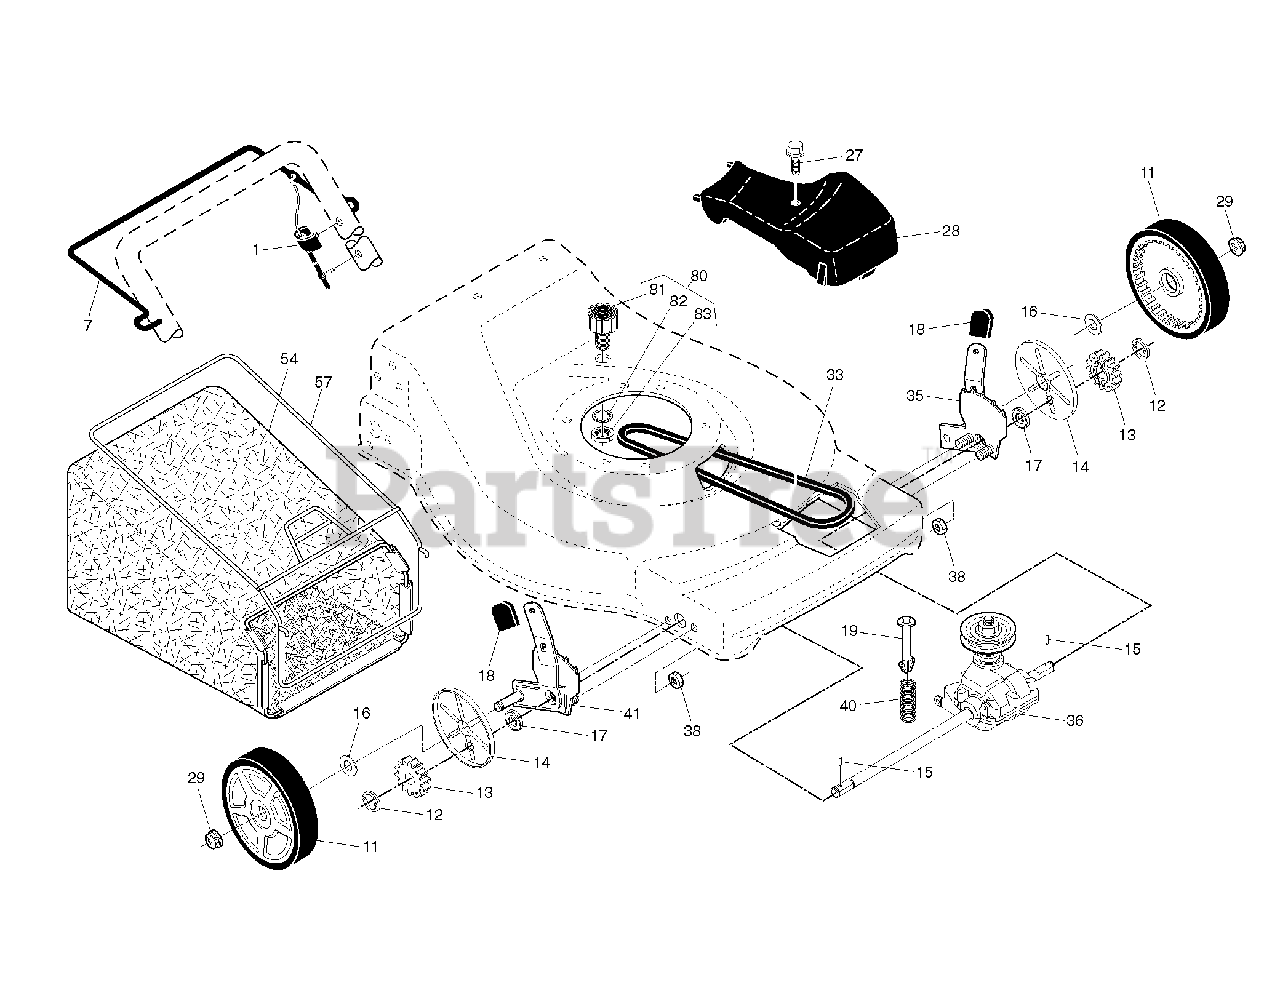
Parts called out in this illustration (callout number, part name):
1	CONTROL.DRIVE.S/SPEED.FWGD
7	BAIL.DRIVE.S/S.ROUND.MARI.21
11	RP.WHEEL.8X1.75.5SPK.RAD3.BLCK
12	E-RING 7/16 RE
13	PINION.14.TEETH.FGD
14	COVER.DUST.WHEEL
15	PAWL, DRIVE
16	WASHER FLUT
17	BEARING.ASM.
18	KNOB.ERGO.DLX.PLAS.MARI.MULTI
19	SPRING RETAINER
27	SCREW, HEX HD TAPPING #10-24 1
28	Drive Cover, Torus B&S Black
29	NUT.HEX.FLANGE.3/8-16.LOCKNUT
33	BELT THERM .32
35	KIT ADJUSTER ASM.438151.
36	TRANSMISSION.22.FGD/W/PULLEY
38	LOCKNUT.NYLOC.1/4-20
40	SPRING.EXTENSION
41	KIT ADJUSTER ASM.438148
54	GBAG.87510416S.BLK.PPR*SUBS/
57	Grass Bag Frame, 22" EZ Empty SC
80	KIT.WASH-OUT.PORT
81	FITTING, HOSE, WATER WASHOUT
82	WASHER.LOCK.INTERNAL.TOOTH
83	LOCKNUT.HEX.WITH.O-RING
